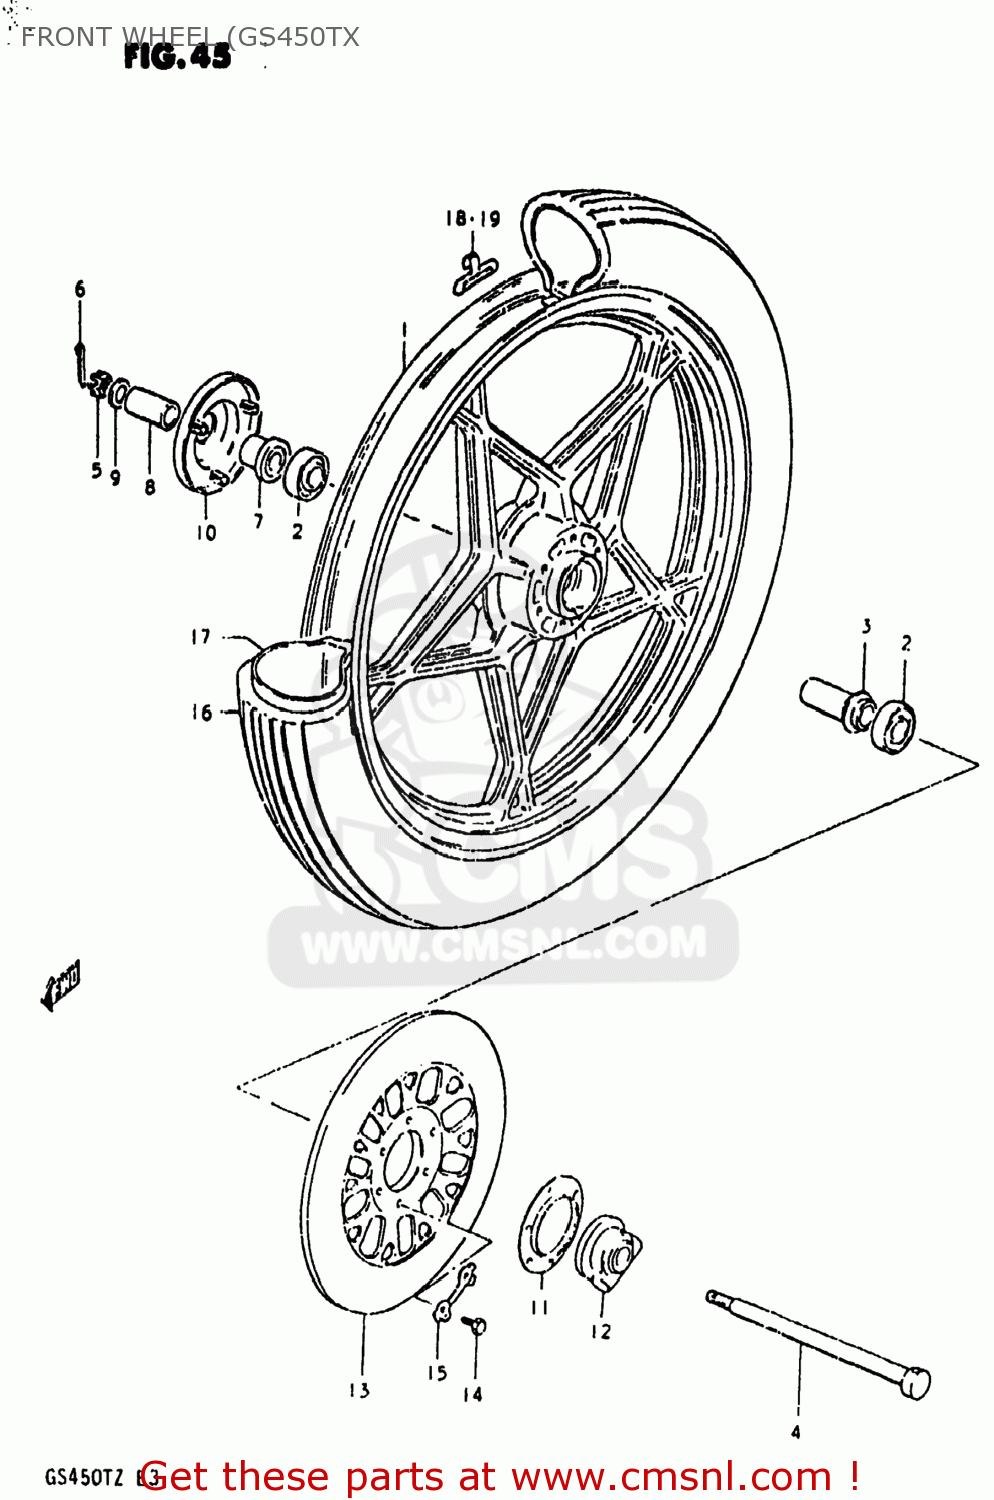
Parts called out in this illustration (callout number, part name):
1	CASTING WHEEL,FRONT 1.85
2	BEARING
3	SPACER,FR HUB BEARING
4	AXLE,FRONT
5	NUT 12MM
6	COTTER PIN
7	SPACER,FR HUB BEARING,R
8	SPACER(15X22X30)
9	WASHER
10	COVER,FR HUB,R
11	DUST SEAL,SPEEDOMETER GEAR BOX
12	BOX ASSEMBLY,SPEEDOMETER GEAR
13	DISC,FR BRAKE
14	BOLT(8X25)
15	WASHER
16	TIRE
17	TUBE 2.75-19 070-483MM
18	BALANCER,WHEEL
19	BALANCER,WHEEL
